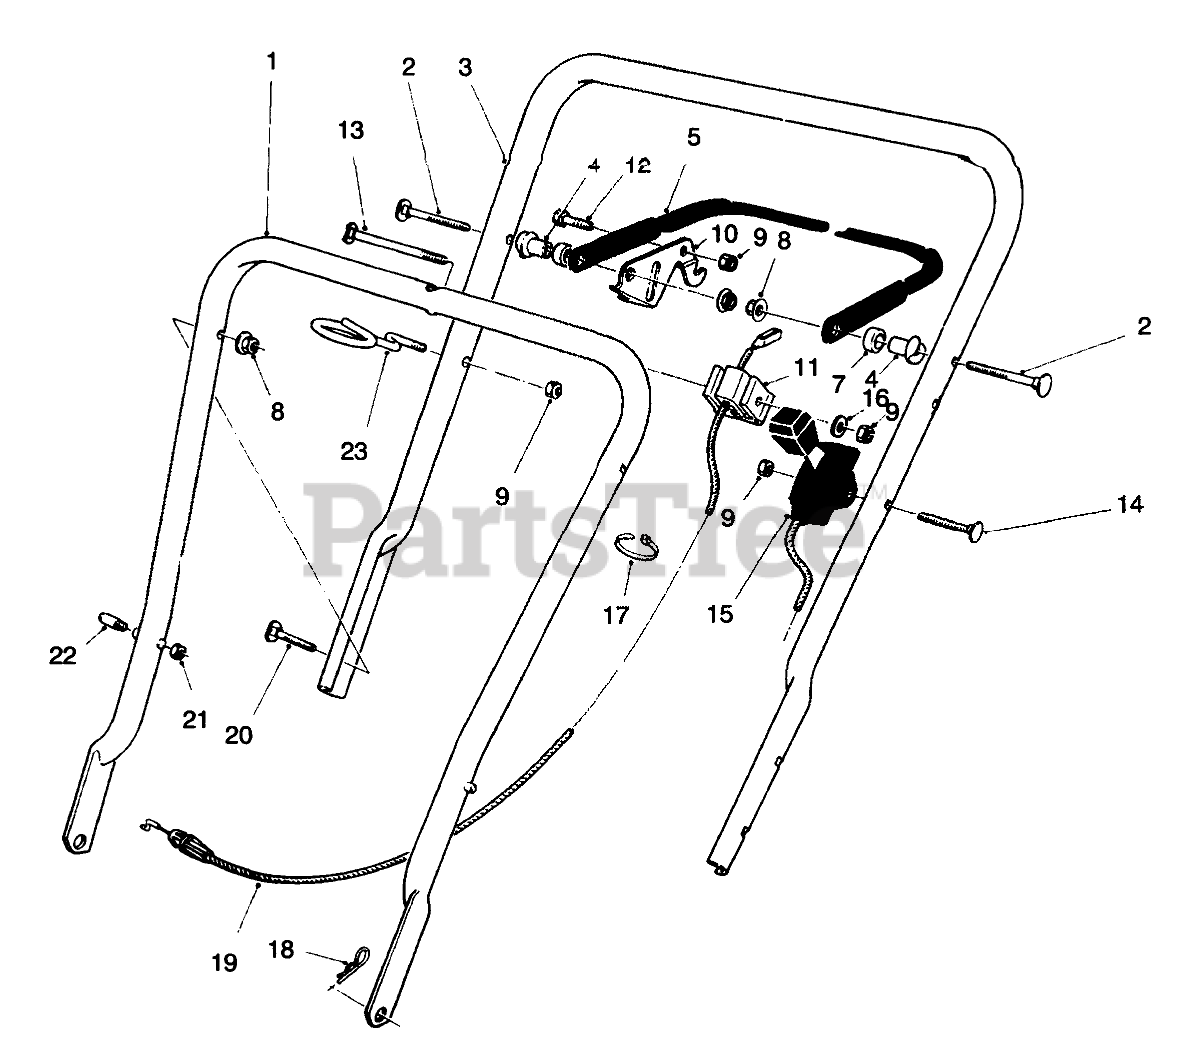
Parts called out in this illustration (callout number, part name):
1	Lower Handle Assembly
2	SCREW-HANDLE
3	UPPER HANDLE
4	SPACER-SUPPORT
5	Bar-Control
7	SPACER-NYLON
8	NUT-LOCK NI
9	NUT-LOCK, NI
10	CONTROL LEVER
11	SUPPORT-CABLE
12	SCREW-HH
13	SCREW-HANDLE
14	SCREW-HANDLE
15	THROTTLE CONTROL
16	WASHER-FLAT
17	TIE-CABLE
18	PIN-COTTER, HAIR
19	BRAKE CONTROL CABLE
20	SCREW-HANDLE
21	NUT-LOCK, NI
22	HANDLE PIN
23	GUIDE-ROPE
